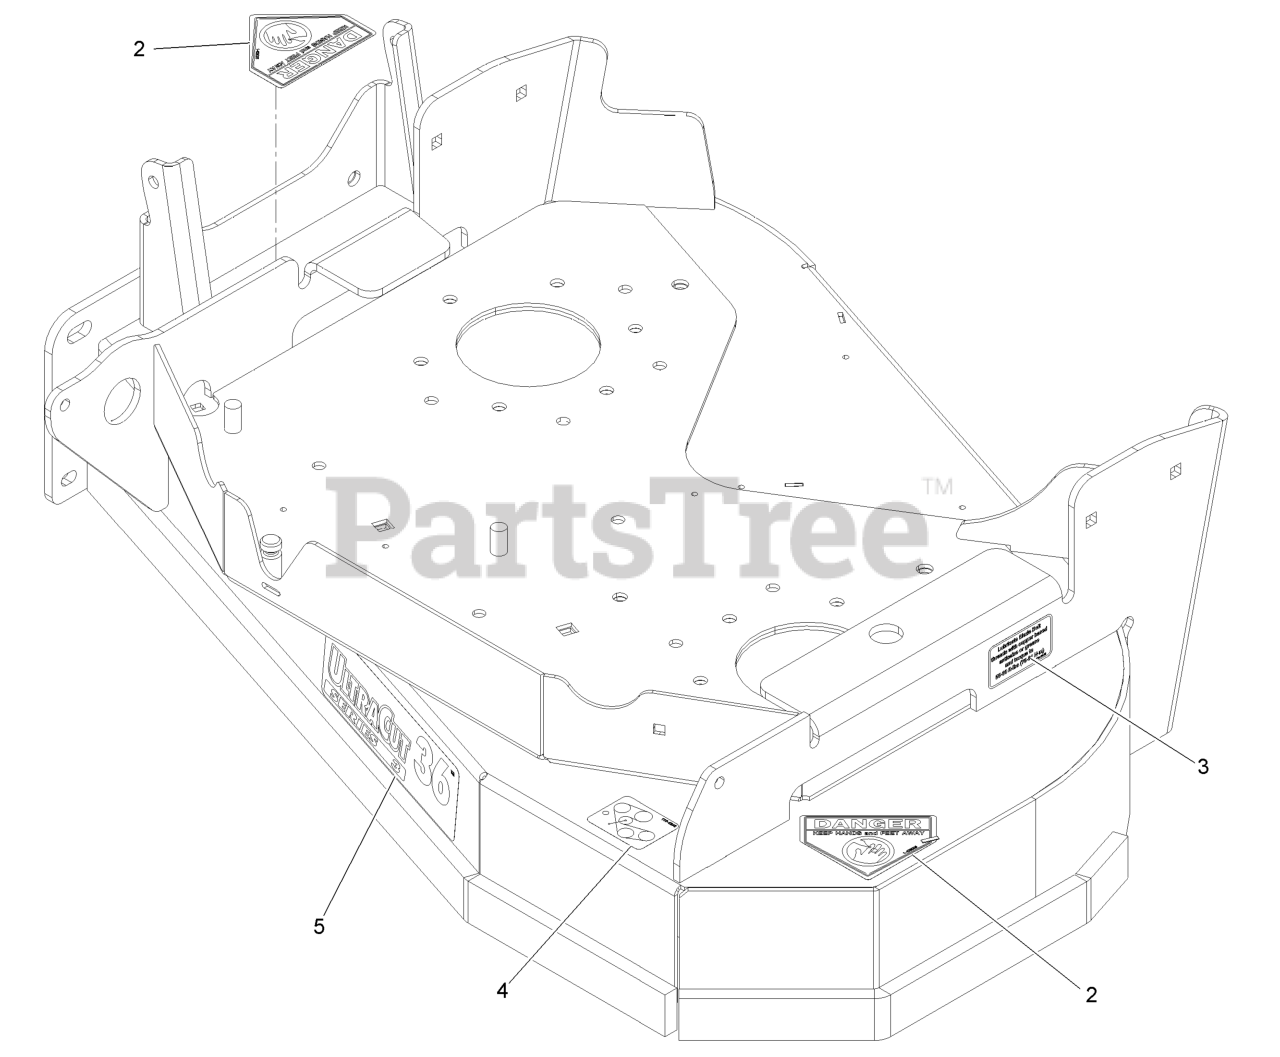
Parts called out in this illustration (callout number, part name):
2	DECAL-DANGER
3	DECAL,BOLT TORQUE
4	DECAL-BELT ROUTING 36
5	DECAL-ULTRACUT 36 SERIES
